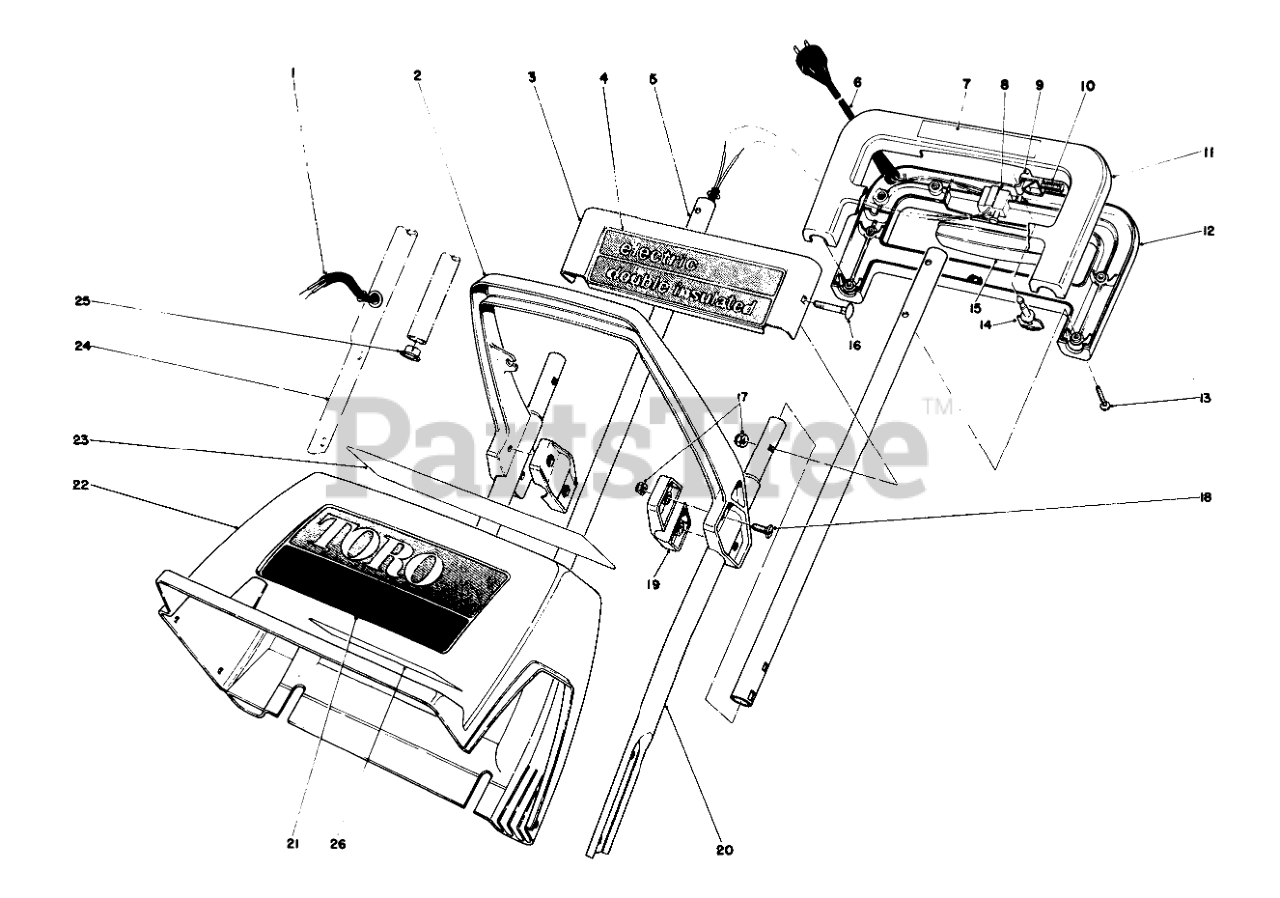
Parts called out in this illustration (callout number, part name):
1	WIRE HARNESS S-120
2	Middle Handle
3	Escutcheon Plate
4	Decal-Electric
5	UPPER TUBE, S-120
6	Cord Supply
7	Decal-Handle
8	SWITCH-STARTER
9	LOCKOUT, 1200
10	COMP SPRING
11	UPPER CONTRL HANDL HID
12	LOWR CONTRL HANDL HID
13	Screw
15	SWITCH BAR, 1200 PC
16	Bolt-Carriage
17	NUT-LOCK, NI
19	Clamp-Middle Handle
20	LOWER TUBE, LH, S-120
21	Decal-Toro S-120
22	Shroud-S-120
23	Decal-UL
24	LOWER TUBE, RH, S-120
25	1200PC-TUBE BUSHING
26	Decal-Danger
